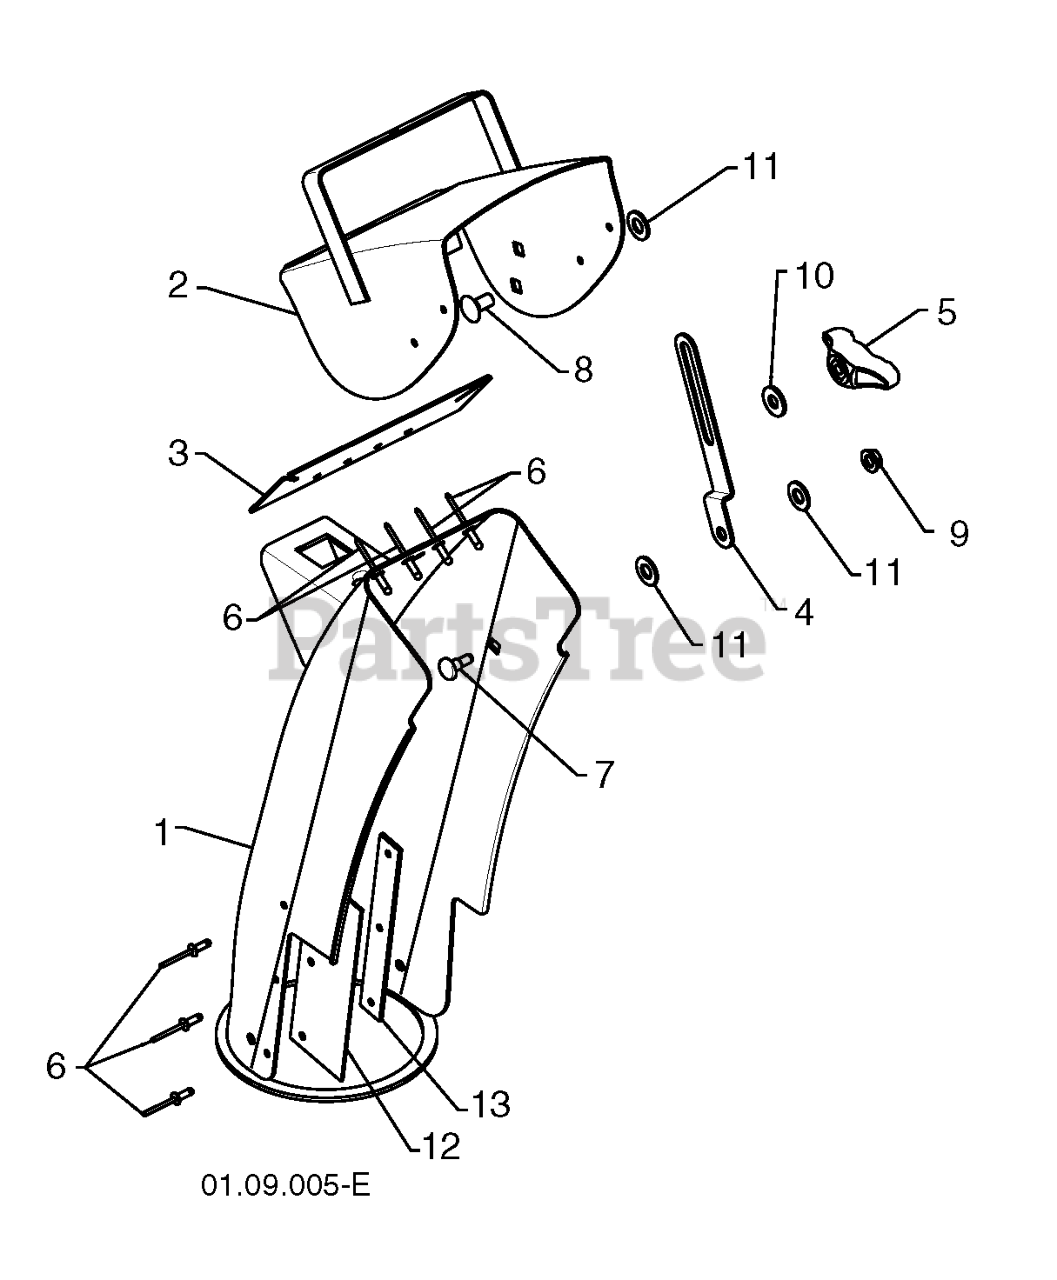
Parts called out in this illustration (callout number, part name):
1	RP CHUTE.WELDMENT.PNT.ORANGE
2	DEFLECTOR.WELDMENT.PNT.ORANGE
3	SEAL.DEFLECTOR
4	STRAP, CHUTE
5	KNOB, DEFLECTOR
6	RIVET BLIND
7	SHOULDER BOLT
8	BOLT
9	NUT.HEX.FLANGE.1/4
10	WASHER.20X8.5
11	WASHER, NYLON FRICTION
12	SHIELD.SNOW.CHUTE
13	RP STRAP.SHEILD.RETAINER
